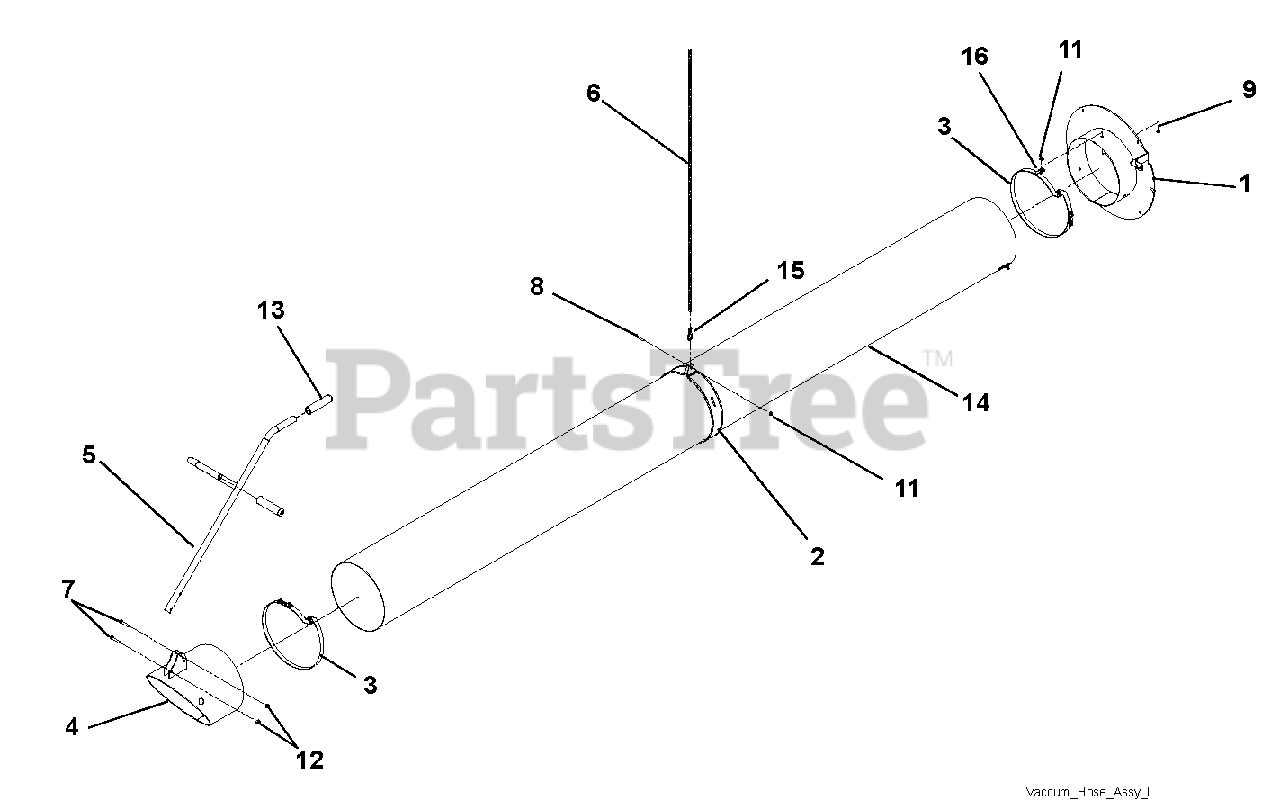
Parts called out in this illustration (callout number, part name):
1	Weldment, Cover Plate (995042)
2	Band, Hose Support 12" (995042)
3	Clamp, Bridge 12" (995042)
4	Weldment, Tube Pickup 12" (995042)
5	Weldment, Handle, Truck Loader
6	Chain, .148 x 5’
7	Bolt, Hex .312-18 x 1.75 Grade 5 YWZC
8	Bolt, Hex .25-20 x 1.75 Grade 5 YWZ
9	Bolt, Round Head Square Neck .25-20 x 1.00 Grade 5 YWZ
11	Nut, .25-20 Nyloc Flange
12	Nut, .31-18 Nyloc Flange YXCZ
13	Grip, Handle
14	Hose, 12" x 12’ Clear (995042)
15	Hook, Spring 2450S-3/16"
16	Clip, Hose
